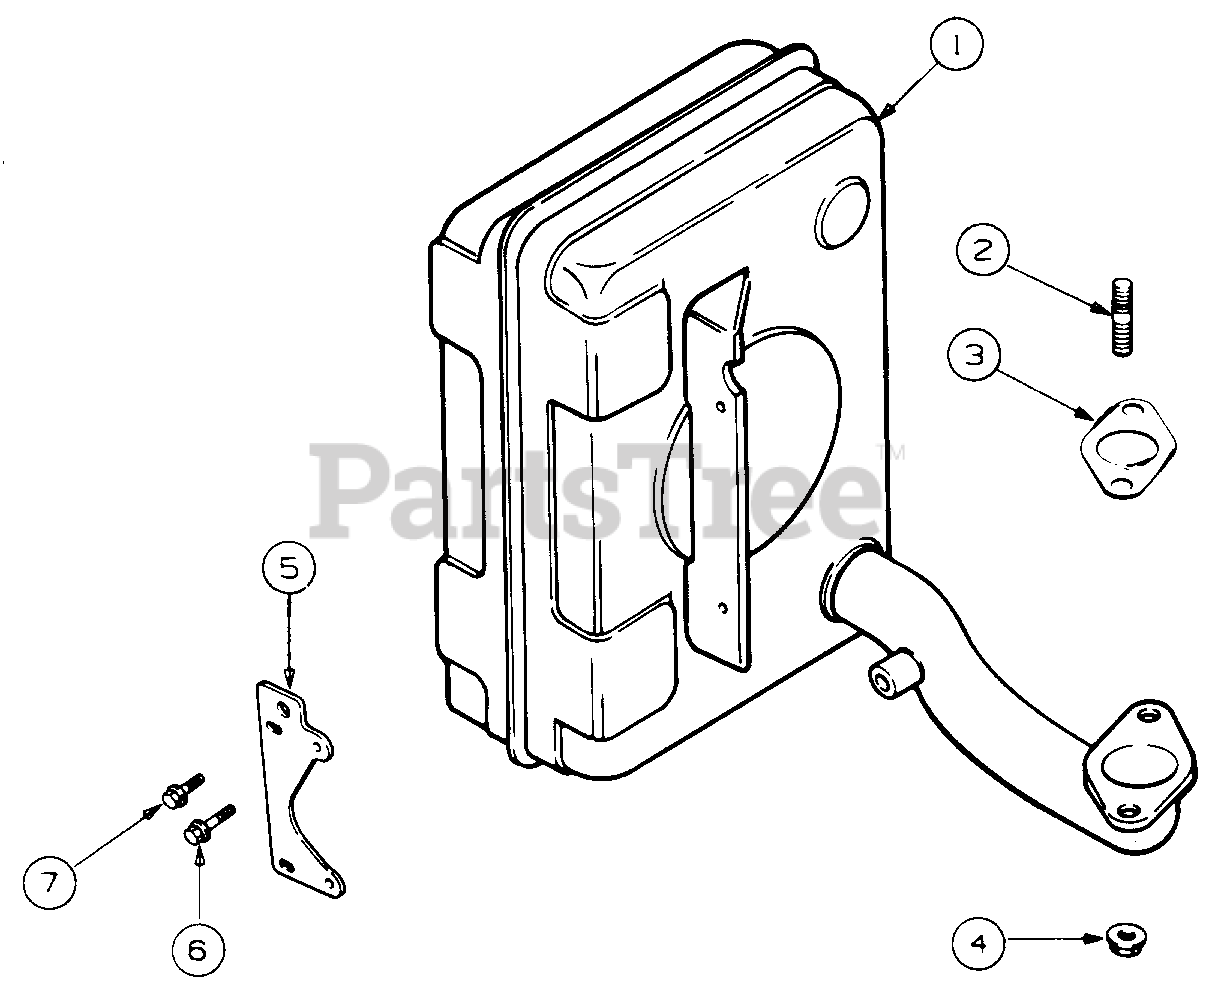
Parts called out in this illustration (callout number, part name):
2	Stud, Exhaust Manifold, M8 X 1.25 X 20
3	Gasket, Exhaust Manifold
4	Nut, Muffler, M8 X 1.25
5	Bracket, Muffler
6	Screw, Muffler Bracket
7	Screw, Valve Cover
